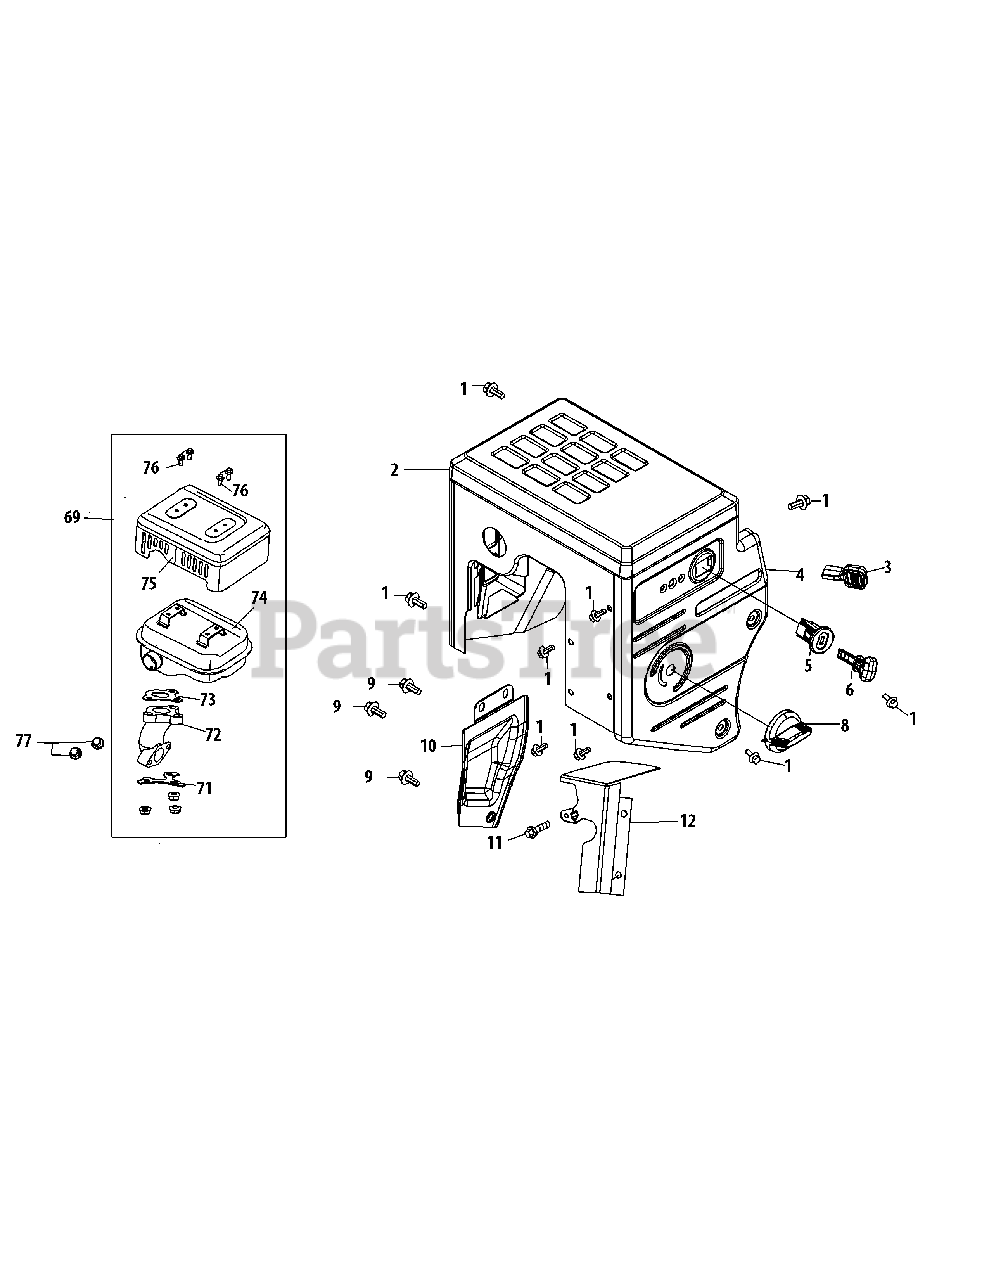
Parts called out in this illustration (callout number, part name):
1	BOLT M6×12
2	MUFFLER SHIELD
3	THROTTLE CONTROL KNOB
4	CONTROL PANEL
5	ENGINE SWITCH BASE
8	CHOKE KNOB
9	BOLT M6×10
10	EXHAUST PIPE SHIELD
11	BOLT M6×16
12	CARB ISOLATOR BRACKET
69	MUFFLER ASSEMBLY
71	NUT-RET EXHAUST BGBLK
72	EXHAUST PIPE
73	GASKET, MUFFLER
74	MUFFLER BODY
75	MUFFLER GUARD
77	NUT, M8
